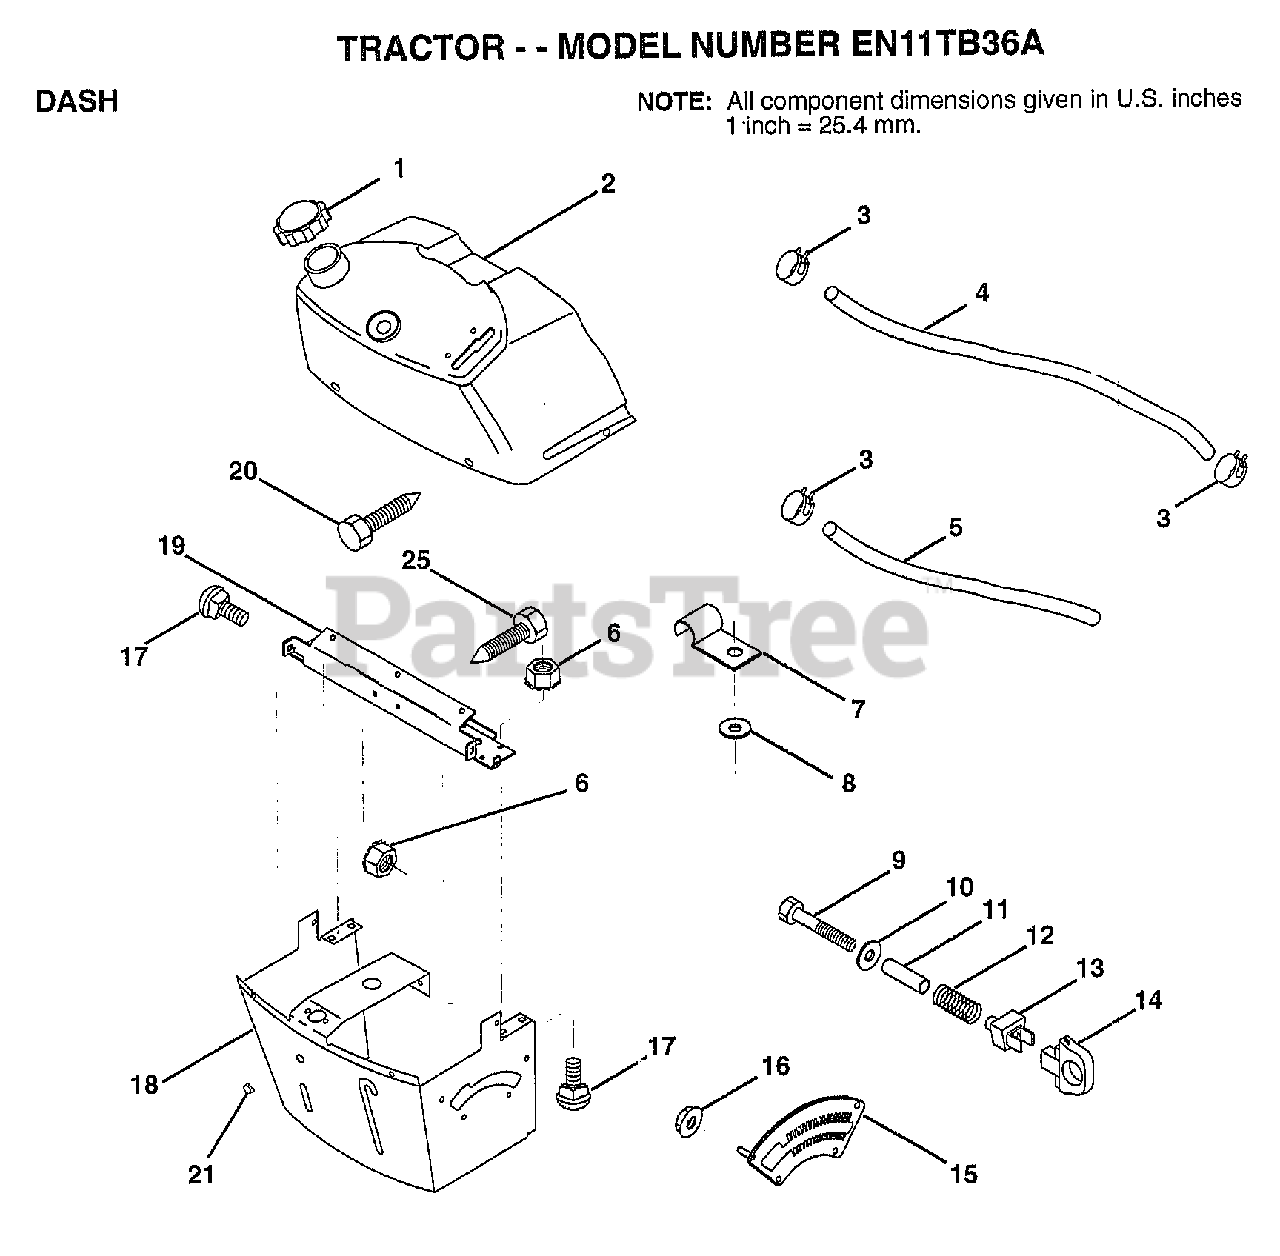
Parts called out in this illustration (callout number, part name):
1	CAP BLK FUEL LR
2	TANK.ASM.DASH.LR
3	HOSE CLAMP
5	FUEL LINE T
6	NUT HXKEP 1/4X20
7	CLIP T
8	WASHER PM
9	BOLT
11	SPACER SPLIT
12	SPRING M
13	"KNOB,HGT RETAINER"
14	KNOB
15	ADJUSTER QUAD
16	NUT
17	BOLT
18	SUPT ASSY DASH
19	CROSS BRACE
20	SCREW.1/4-20X1/2
21	PLUG DOME
25	SCREW LT
